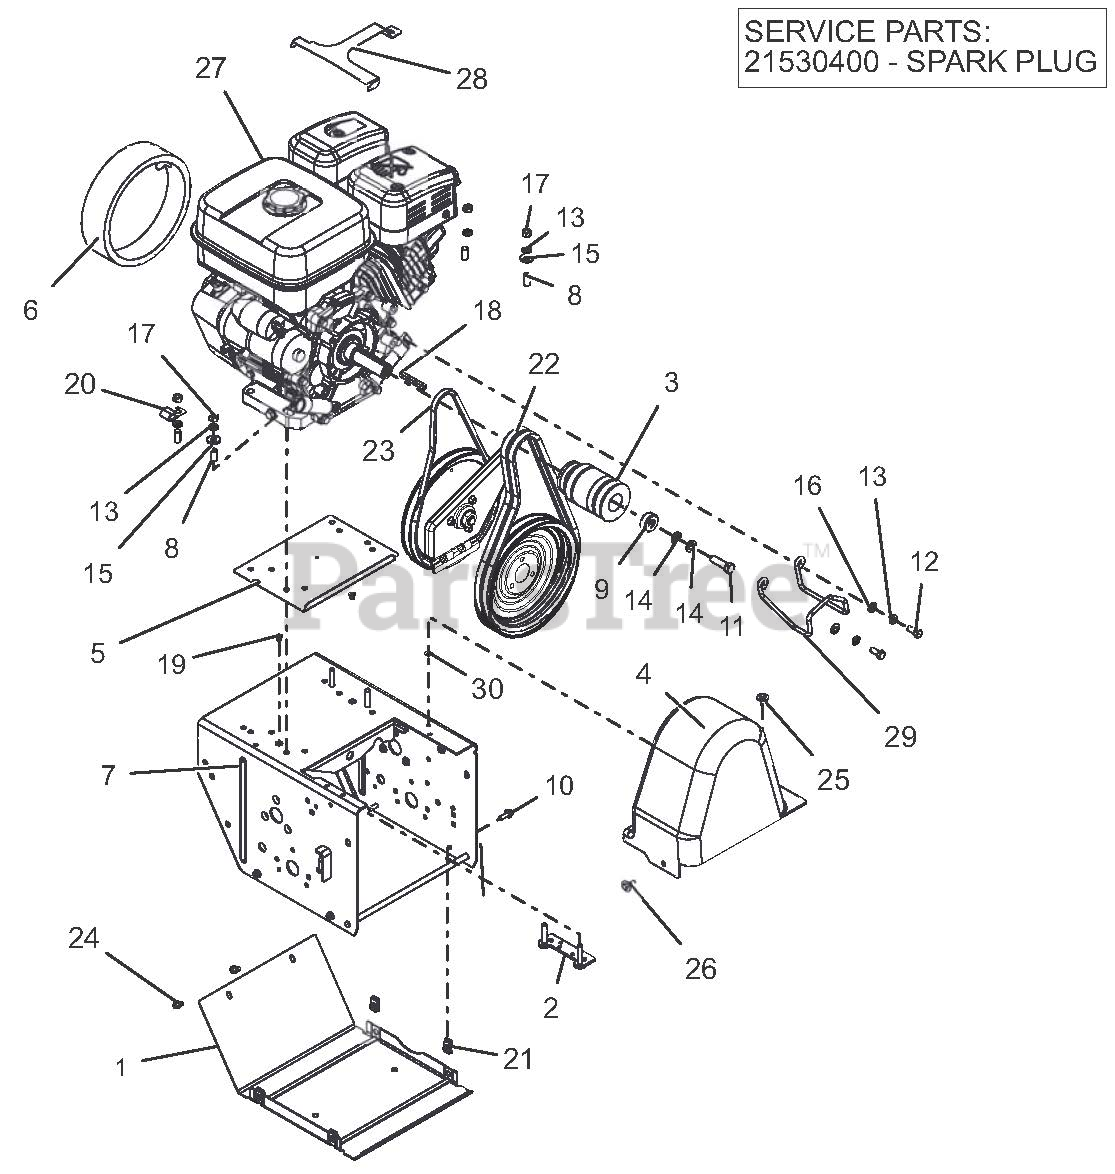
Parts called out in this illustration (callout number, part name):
1	COVER, BOTTOM
2	STRAP, ENGINE BOLT-LARGE BRIGGS
3	SHEAVE, ATTACHMENT 2-GRV
4	COVER, BELT - TALL PRO
5	BAFFLE, WATER - PRO SERIES
6	COVER, FOAM - SUBARU RECOIL
7	FRAME, MAIN - PRO HYDRO
8	BSHG-SLV .325X.400X.795
9	BSHG, -- SPACER .47X1.25X.5
10	BLT-HEX .25-20X.75 HWH YWZC GR5
11	BLT-HEX .44-20X1.50 GR8 YWZC
12	BLT-HEX .31-24X.75 GR5 YWZC
13	WSHR-LK .31X.097 HVY YWZC
14	WSHR-LK .44X.109 REG YWZC
15	WSHR-FL-STL.38X.875X.083 YWZC
16	WSHR-FL-STL.344X.688X.065YWZC
17	NUT-HEX .31-18 YWZC
18	KEY, .25X.25X2.25
19	RVT-POP .187x.250 (#64) YWZC
20	CLAMP, J
21	NUT, RTNR .25-20 X .56
22	V-BELT, HA-RAW EDGE (SET)
23	V-BELT, 3L-RAW EDGE
24	SCR-TAP .25-20X.50 HWH TR YWZ
25	SCR, TAP .25-20X.50 LGHWH TR
26	SCR, TAP .25-20 X.5 CAPTIVE
27	ENGINE, SUBARU EX27 AS 120V
28	GUARD, SNOW- SUBARU
29	FINGER, BELT - HYDRO TRACK
30	NUT, PUSH .25X.50 O.D.
31	SPARK PLUG
